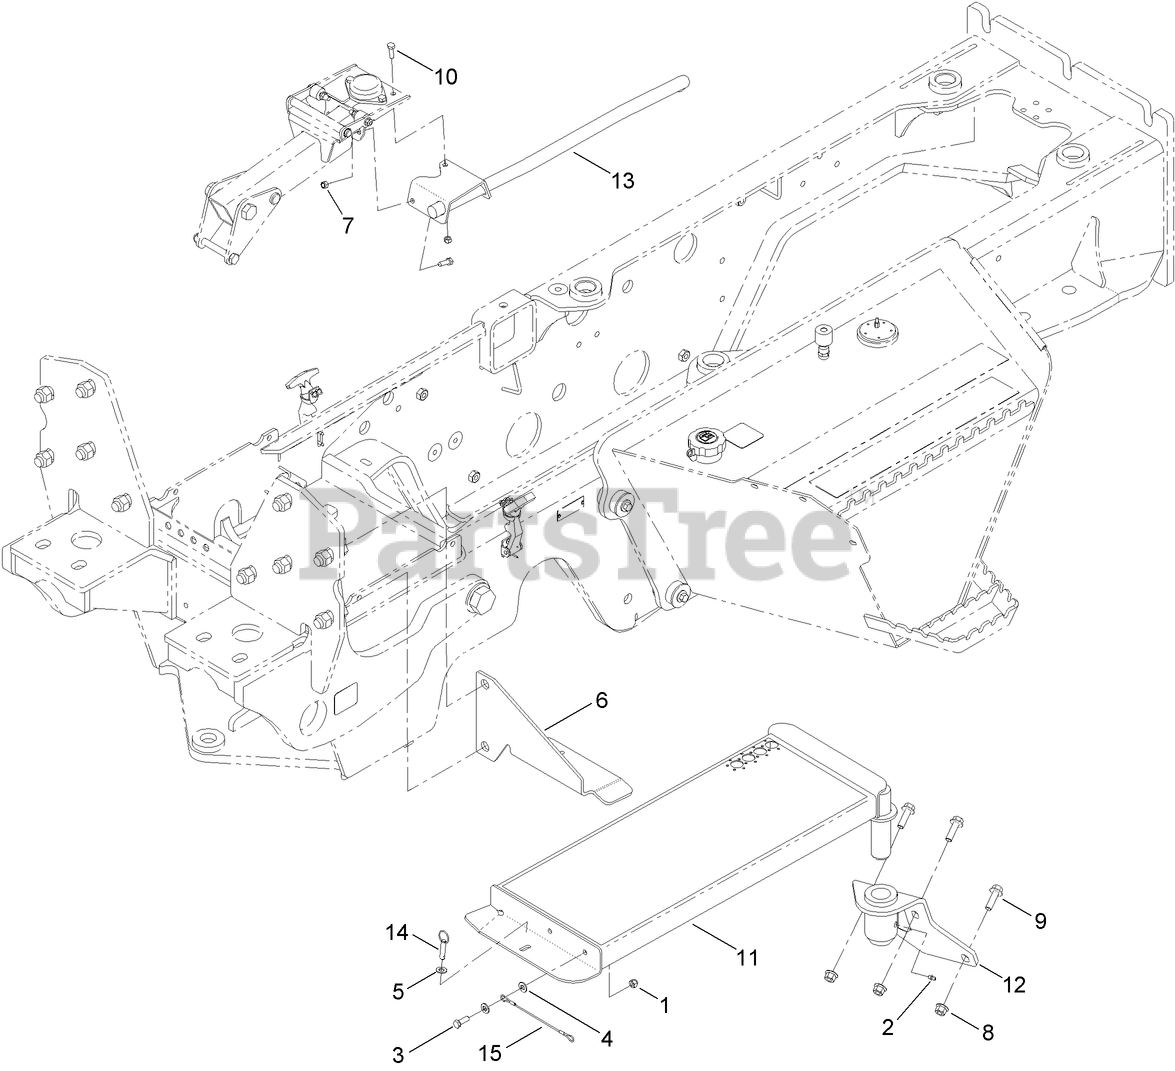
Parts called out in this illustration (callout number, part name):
1	NUT-HEX
2	FITTING-GREASE
3	SCREW-HH
4	WASHER-FLAT
5	WASHER-FLAT
6	BRACKET-SUPPORT, WALKWAY
7	NUT-LOCK, NI
8	NUT-LOCK, HHF
10	SCREW-HH
11	WALKWAY-BACKHOE
12	MOUNTING-BRACKET, WALKWAY
13	HANDRAIL-BACKHOE
14	PIN-Cotterless
15	RETAINER-ROPE, WIRE
